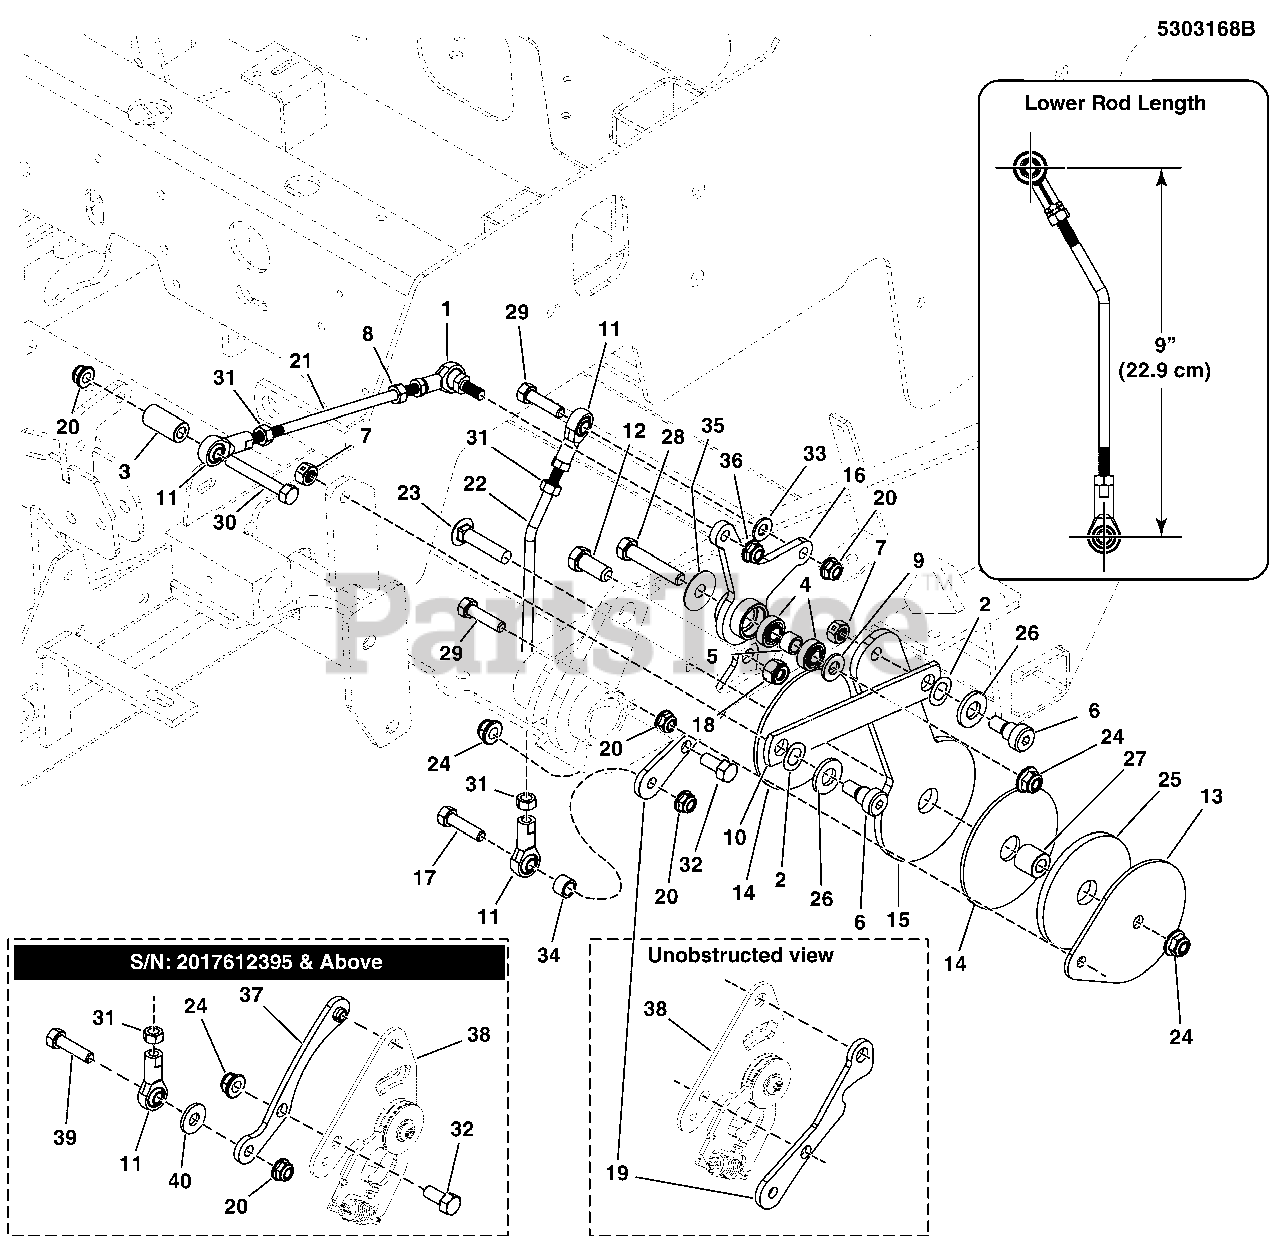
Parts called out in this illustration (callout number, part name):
1	BALL JOINT, 5/16-24 LH FEMALE W/STUD, BR
2	WAVE WASHER, 1/2"ID X 087"OD X .01 THK.
3	SPACER, .33 X .63 X 1.25, CZ
4	BEARING, .375" ID X .875" OD X .341" THK
5	SPACER, .39 X .55 X .38, CZ
6	BOLT, 3/8-16 X 3/8, 1/2 SHOULDER
7	NUT, 3/8-16 HEX SIDE LOCK
8	NUT, 5/16-24 HEX, LH
9	WASHER, 3/8 GD.9 FLAT
10	LINK, CONTROL SYSTEM ARM, IS700 - BLK
11	BALL JOINT 5/16-24 RH FEMALE STAMPED STL
12	BOLT, 7/16-14 X 3/4, GD 5 YZ
13	PLATE, CONTROL SYSTEM LOCK - BLK
14	PAD, CONTROL SYSTEM
15	PLATE, CONTROL SYSTEM ARM - HT
16	PIVOT, CONTROL SYSTEM
17	BOLT, 5/16-18 X 1-1/2 GD5 YZ
18	NUT, 7/16-14 HEX NYLON LOCK
19	REPLACE WITH COMPONENTS IN S/N: 2017612395 & ABOVE RANGE
20	NUT, 5/16-18 HEX NYLOCK FLANGE
21	ROD, HYDRO LINKAGE, 7.75, CZ
22	ROD, CONTROL SYSTEM, IS700, CZ
23	BOLT, 3/8-16 X 1-1/2, CARRIAGE, GD5, CZ
24	NUT, 3/8-16 HEX NYLOCK FLANGE
25	PAD, .77 X 3.50 X .25, POLYURETHANE
26	WASHER, 1/2 GD9 YZ
27	SPACER, .39 X .75 X .69, CZ
28	BOLT, 3/8-16 X 2 GD5 YZ
29	BOLT, 5/16-18 X 1-1/4 GD5 YZ
30	BOLT, 5/16-18 X 2-1/2 GD5 YZ
31	NUT, 5/16-24 HEX
32	BOLT, 3/8-16 X 3/4 GD5 YZ
33	WASHER, 5/16 F436 FLAT
34	SPACER, .33 X .625 X .360
35	WASHER-3/8 FENDER
36	NUT, 5/16-24 HEX NYLON LOCK
37	CONTROL ARM, ZT3400
38	TRANSAXLE CONTROL ARM (PART OF TRANSAXLE)
39	BOLT, 5/16-18 X 1-1/4 GD5 CZ
40	WASHER, 5/16 SAE
